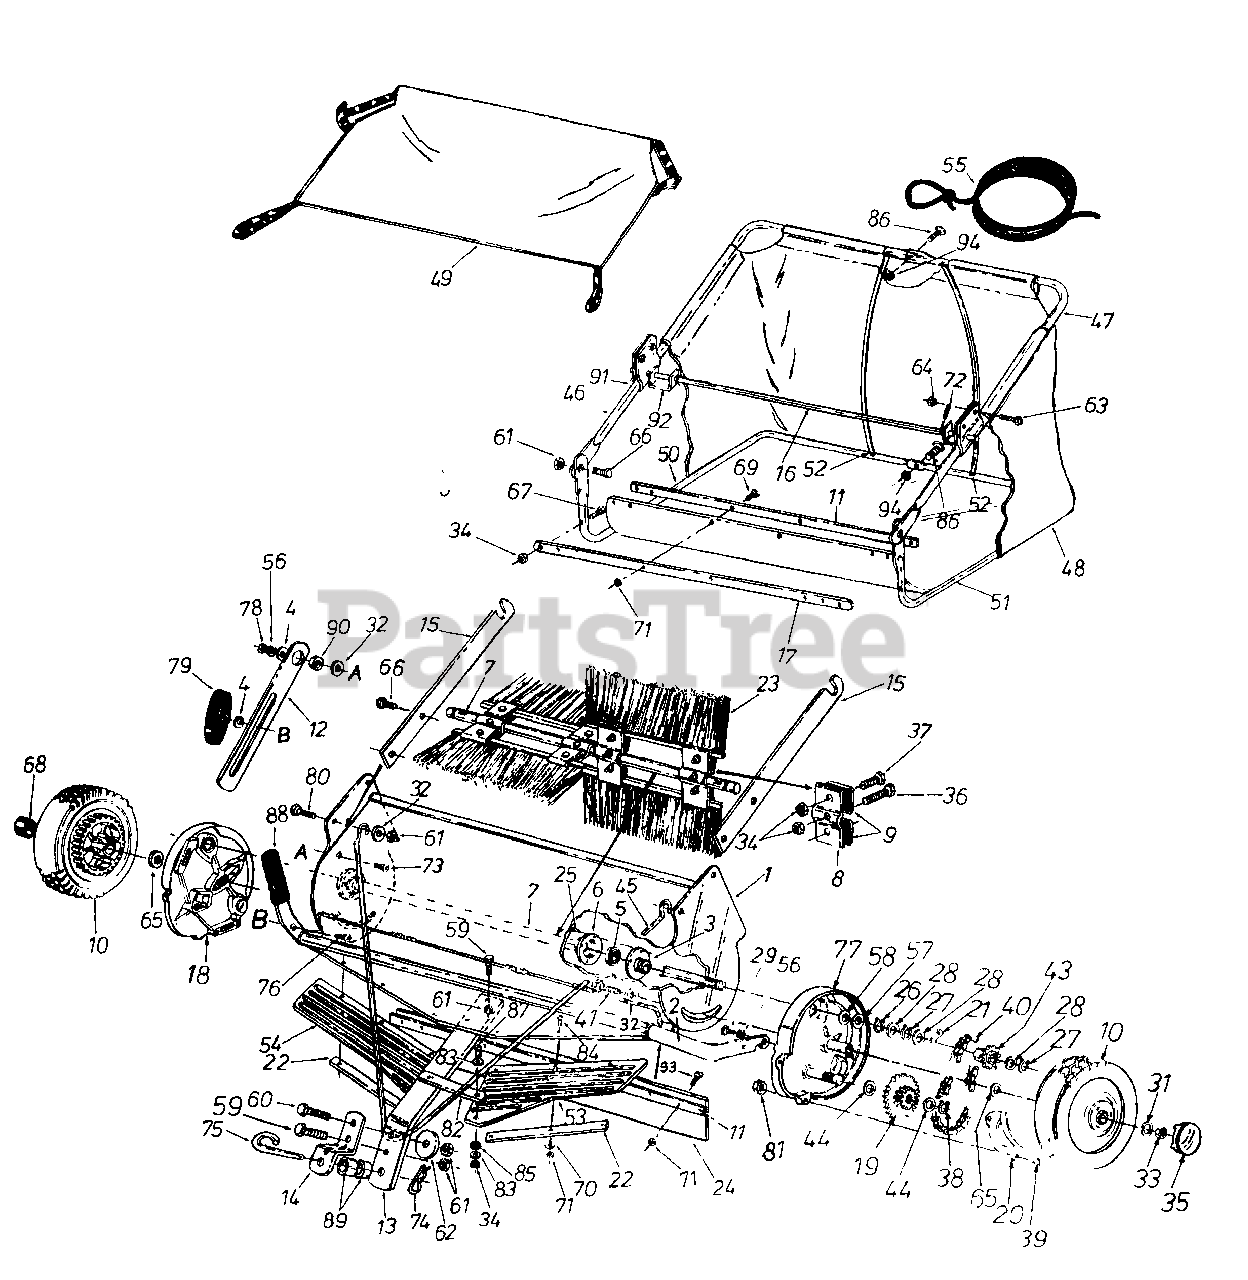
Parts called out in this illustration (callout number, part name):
1	Sweeper Housing Ass'y.
2	Adjustment Rod Ass'y.
3	Brush Bushing Ass'y.
4	Washer, 5/16" Std.
5	Ball Bearing .596 I.D.
6	Bearing Retainer
7	Brush Shaft - 38"
8	Brush Retainer - Double
9	Brush Retainer - Single
10	Wheel Ass'y. Complete
11	Skirt & Bag Retainer - 38"
12	Weight Adjustment Strap
13	Hitch Bar
14	Hitch Bracket
15	Hopper Mount Arm
16	Hopper Bag Pivot Rod
17	Bag Frame Strap
18	Housing Wheel Drive Ass'y. (R.H.)
19	Gear Sprocket Sub. Ass'y.
20	Dust Cover
22	Shield Retainer
23	Sweeper Brush
25	Pop Rivet
26	Retaining Ring - 3/4"
27	Retaining Ring - .594" I.D.
28	Shim Wash .596 x 1.125 x .025
29	Hex Bolt 5/16 x 3/4" Lg.
31	Fl.-Washer .38 x 1.25 x .06
32	Washer, 3/8" Std,
33	Hex Lock Nut 3/8-24 Thd.
34	Hex Lock Nut 1/4-20 Thd.
35	Hub Cap
36	Hex Bolt 1/4-20 x 1.0" Lg.
37	Hex Bolt 1/4-20 x 3/4" Lg. (Gr. 5)
38	Retaining Ring - 1/2"
39	Pan Hd. Screw #10-32 x 1" Lg.
40	Roller Chain 3/8 x 1/2-40
41	Hex Bolt 3/8-24 x 3-1/4" Lg. (Gr. 5)
43	Ratchet Sprocket L.H. - 11 T.
44	Washer .51 x .990 x .02
45	Brace Rod
46	Upper Hopper Tube - R.H.
47	Upper Hopper Tube - L.H.
48	Hopper Bag
49	Wind Screen
50	Lower Hopper Tube - R.H.
51	Lower Hopper Tube - L.H.
52	Hopper Support Rod 34" Lg.
53	Hitch Shield - L.H.
54	Hitch Shield - R.H.
55	Hopper Rope
56	Spring Lock Washer 5/16"
57	Fl.-Washer .78 x 1.25 x .062
58	Fl.-Washer .78 x 1.25 x .031
59	Hex Bolt 3/8-16 x 1" Lg. (Gr. 5)
60	Hex Bolt 3/8-16 x 1-1/2" Lg.
61	Hex Lock Nut 3/8-16 Thd.
62	Fl.-Washer 17-32 x 1-1/2 x 10 Ga.
63	Hex Bolt 5/16 x 3/4" Lg.
64	Hex Lock Nut 5/16-18 Thd.
65	FI.-Washer .78 I.D.
66	Hex Bolt 3/8-16 x 3/4" Lg. (Gr. 5)
67	Hex Bolt 1/4-20 x 1-1/4" Lg.
68	Wheel Bearing
69	Slotted Truss Hd. Scr. #10-32 x 5/8" Lg.
71	Hex Lock Nut #10-32 Thd.
72	Cotter Pin 1/8" x 3/4" Lg.
73	Carriage Bolt 5/16-18 x 3/4" Lg.
74	Hair Pin Cotter
75	Hitch Pin
76	Carriage Bolt 5/16-18 x 3/4" Lg.
77	Housing Wheel Drive Ass'y. (LH)
78	Hex Nut 5/16-18 Thd.
79	Knob, Wing 5/16-18 Thd.
80	Hex Bolt 3/8-16 x 1-1/4" Lg.
81	Hex Lock Nut #10-32 Thd.
82	Rubber Connector Flap
83	Fl. Washer 1/4" Std.
84	Slot Truss Hd. Scr. #10-32 x 5/8" Lg.
85	Nylon Washer 21/64
86	Curved Head Bolt 1/4-20 x 1" Lg.
87	Hex Bolt 1/4-20 x 3/4" Lg.
89	Hitch Adjustment Tube
90	Spacer 13/32 x 5/8 x 3/16
91	Hopper Mounting Clamps
92	Bag Retainer Clevis
93	Slotted Truss Hd. Scr. #10-32 x 1/2" Lg.
94	Nut, Lock Hex 1/4-20 Thd.
